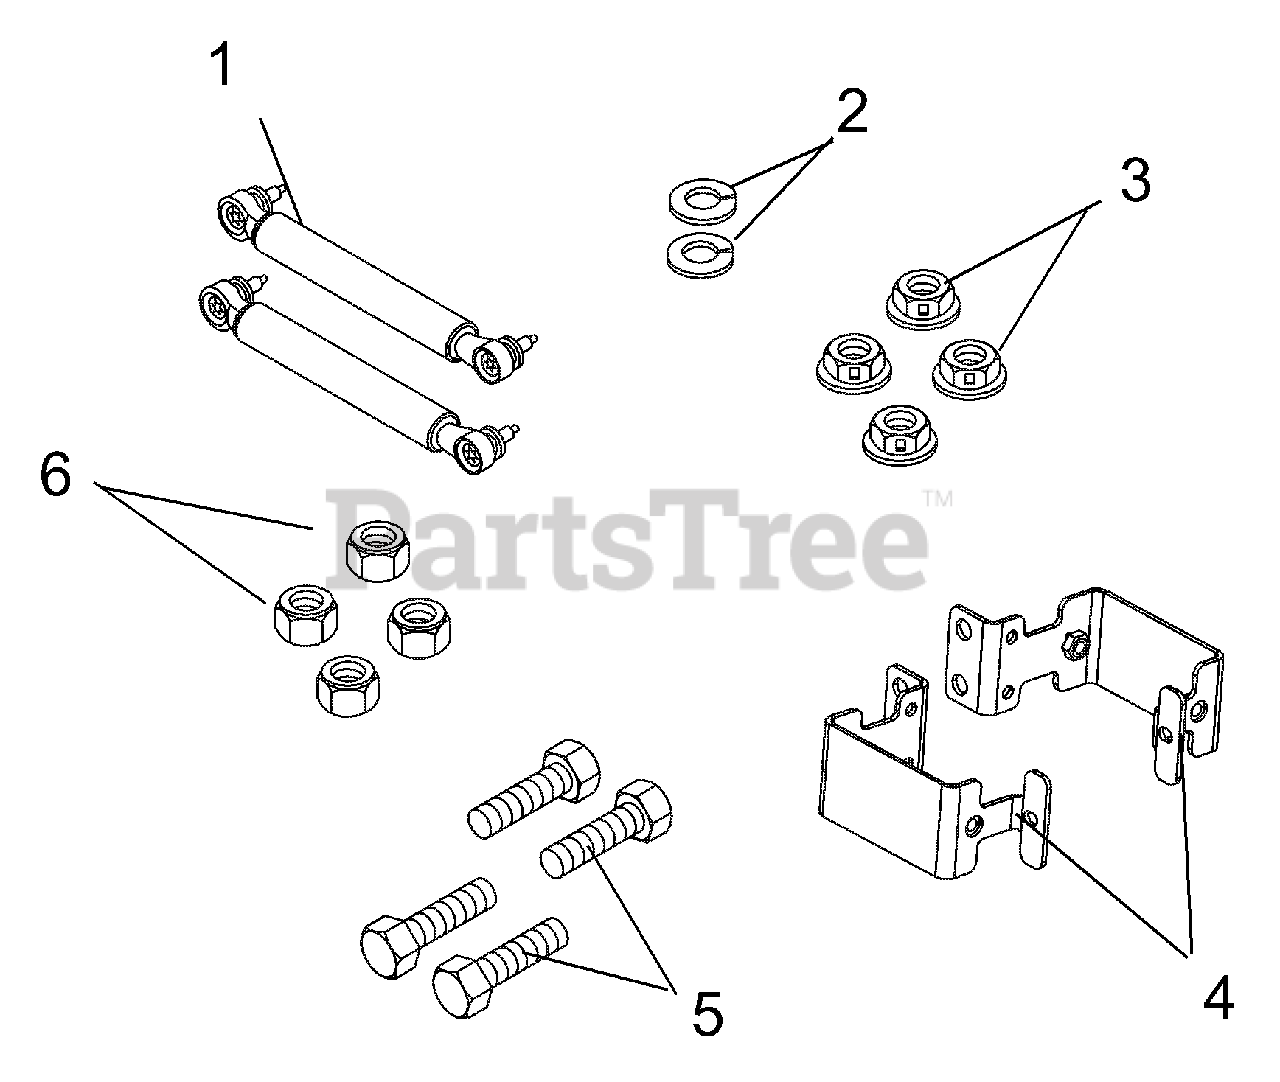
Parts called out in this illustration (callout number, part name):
2	5/16 x 5/64 Lock Washer
3	8 x 1-1/4 Top Locking Flange Nut
4	Steering Stop
5	3/8-16 x 2 Hex Bolt Grade 5
6	3/8-16 Hex Jam Nut
